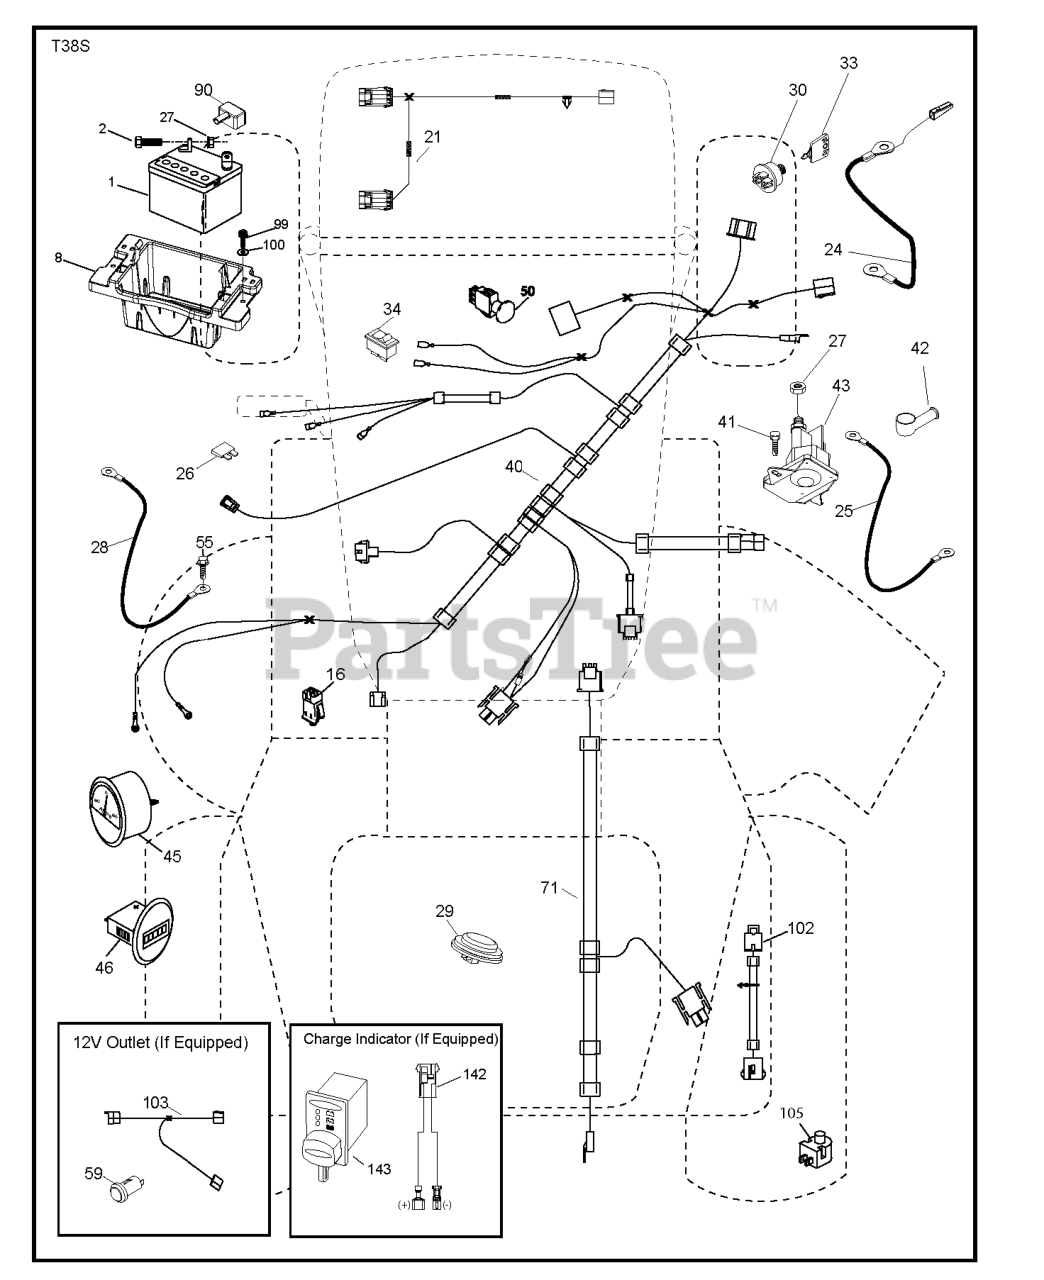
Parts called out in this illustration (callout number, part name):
1	Battery 12 Volt 25 Amp
2	BOLT.HEX.1/4.X.3/4.DICHROMATE
8	TRAY.BATTERY.BOX.FRONT
16	SWITCH INTERLOOK PUSH-IN
21	HARNESS LIGHT ASSY TRACTOR,
24	CABLE.FRBATT.W/WIRE.8GA.8
25	CABLE.STARTER.8GA.17.5
26	FUSE 20AMP
27	NUT
28	CABLE.GROUND.21"BLK.8GA.90T
29	SWITCH.SEAT.DELTA.OPC.
30	SWITCH.IGN.DELTA.W.LGH.ROS
33	KEY.CHAIN.BLISTER.PACK.GEN.INT
40	HARNESS.IGN.DSH.W112V.WPORTWIR
41	SCREW
42	TERMINAL COVER
43	SOLENOID.STARTER.BRASS.PLUNGER
45	GAUGE.AMMETER.SILVER/WHITE
46	GAUGE.HOUR.METER.SILVER/WHITE
50	SWITCH.PTO.8TERMINAL.STD.BLK
55	SCREW 5/16"
59	OUTLET.12-VOLT
71	HARNESS-CHASSIS SUB
90	COVER.TERMINAL.BATTERY
99	SCREW HEXWSHR 1/4-20X3/4
102	HARNESS PIGTAIL PCH TEX ROS
103	HARNESS.PIGTAIL.12V.OUTLET.
105	REVERSE SWITCH
142	CHARGE.PORT.PIGTAIL HARNESS
143	CHARGE.PORT
